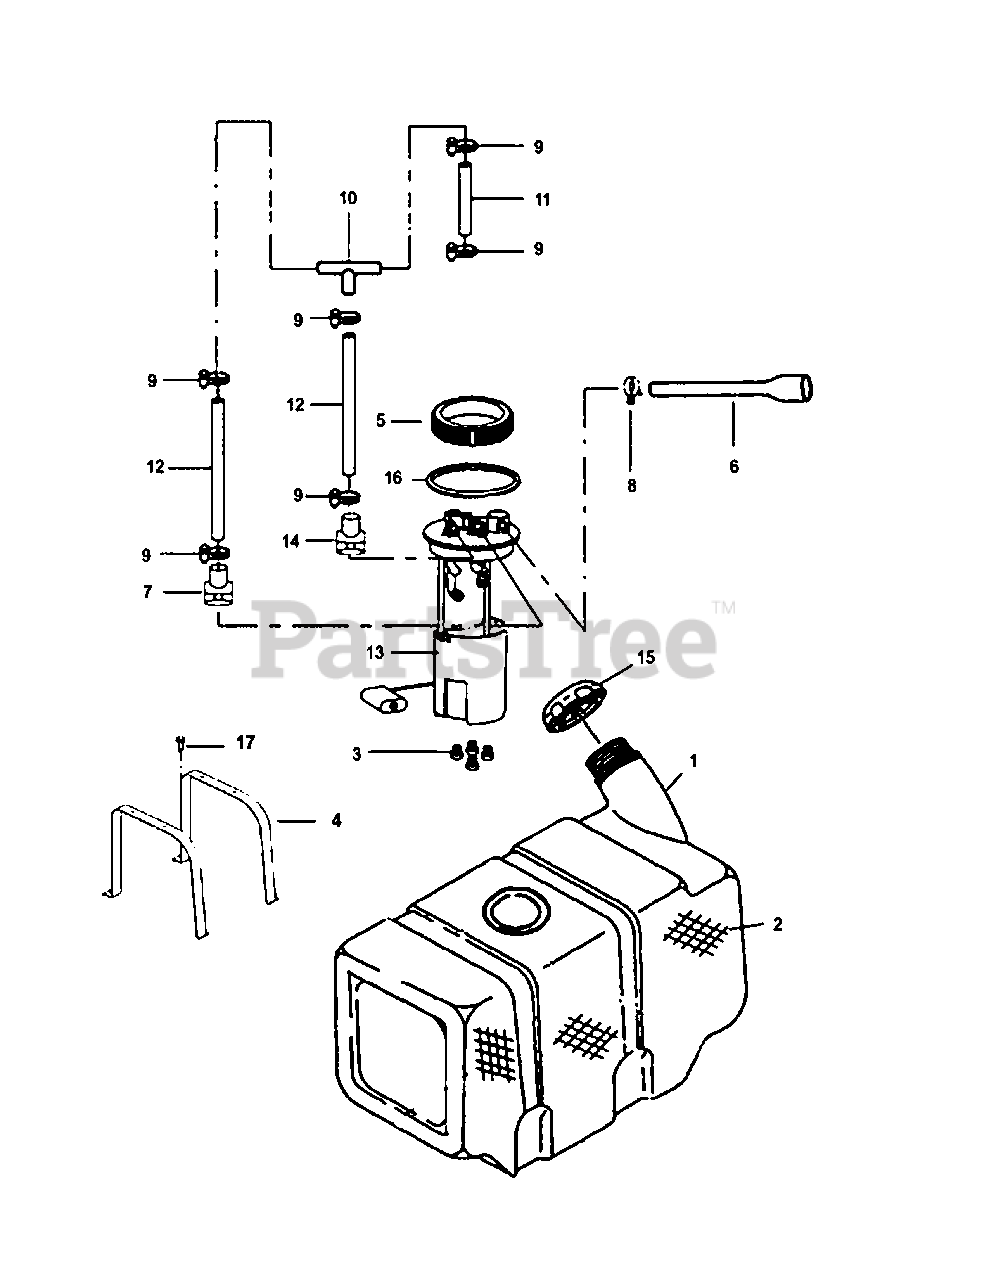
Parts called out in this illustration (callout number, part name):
1	Fuel Tank
2	Insulation Paper IX
3	Shock Absorber Cushion VIII
4	Binder Plate, Fuel Tank
5	Cover, Fuel Pump(EFI Engine)
6	Rubber Tube VI (EFI Engine)
7	Plug For Fuel Outlet(EFI Engine)
8	Clip10
9	Clip
10	Fuel Three-way Pipe
11	High-pressure Fuel Pipe 8×14-885
12	Fuel Pipe 8×14-330(EFI Engine)
13	Fuel Pump Assy(EFI Engine)
14	Plug, Fuel Inlet(EFI Engine)
15	Fuel Tank Cap
16	Seal Gasket For Fuel Pump(EFI Engine)
17	Hexagon Flange Bolt M8×20
